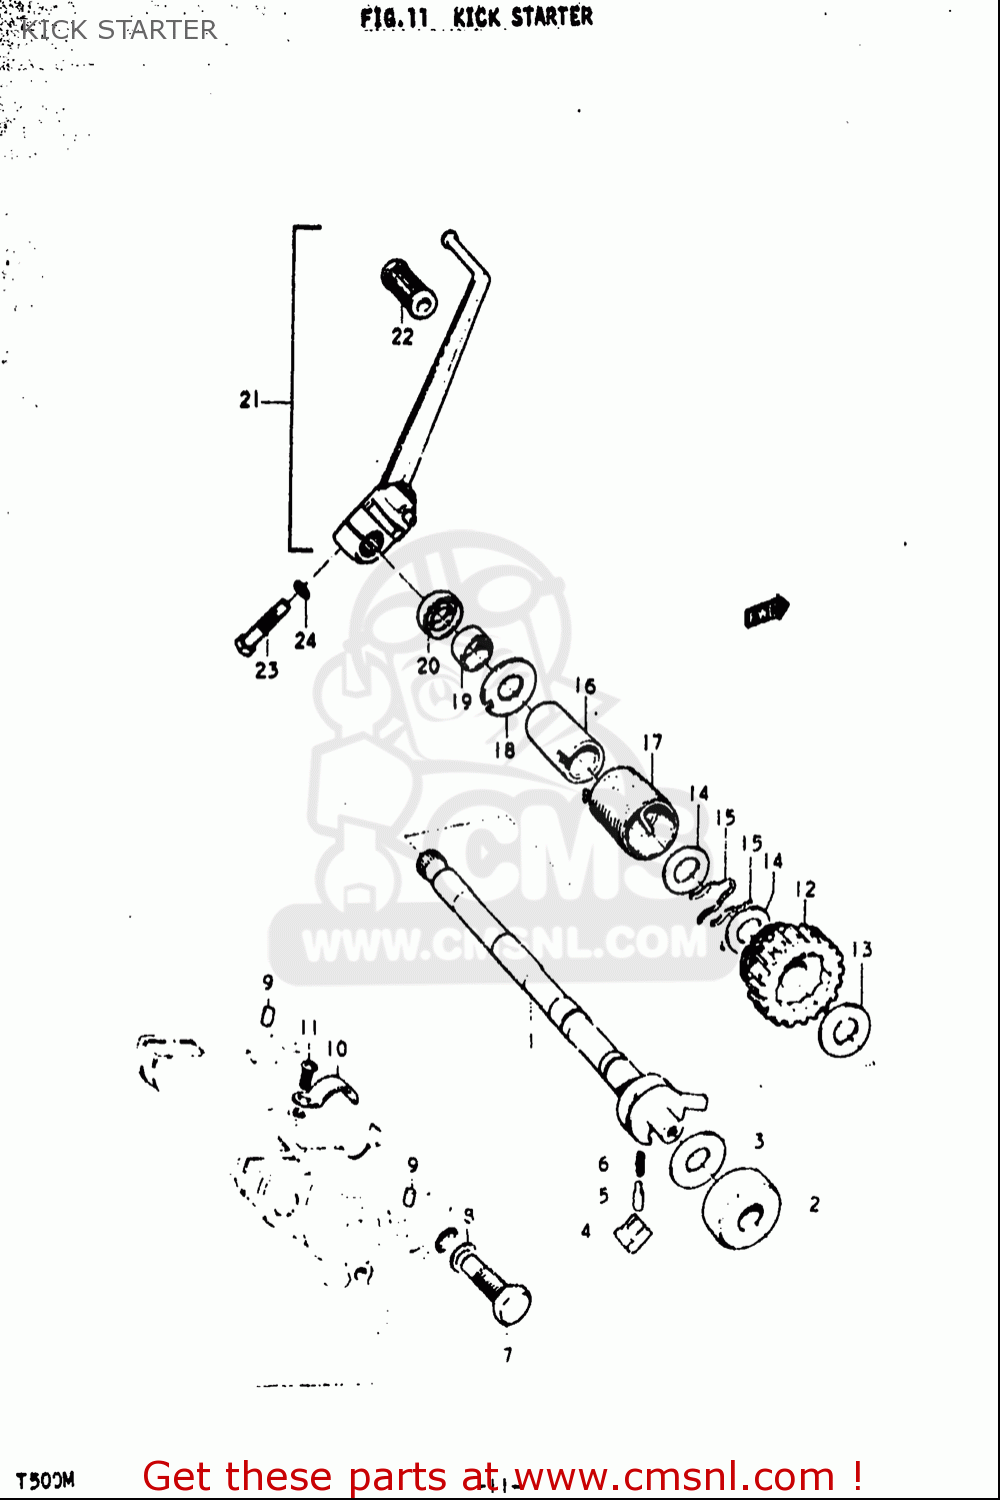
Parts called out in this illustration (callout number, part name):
3	WASHER(13X31.5X1.5)
4	PAWL,KICK STARTER
5	PIN(5X15.5)
6	SPRING
8	WASHER(14.5X22X1.6)
9	PIN
11	SCREW
14	WASHER(16X30X1)
17	SPRING
20	SEAL,OIL(16X30X8)
22	RUBBER,KICK STARTER PEDAL
23	BOLT(10X37.5)
24	WASHER,LOCK
